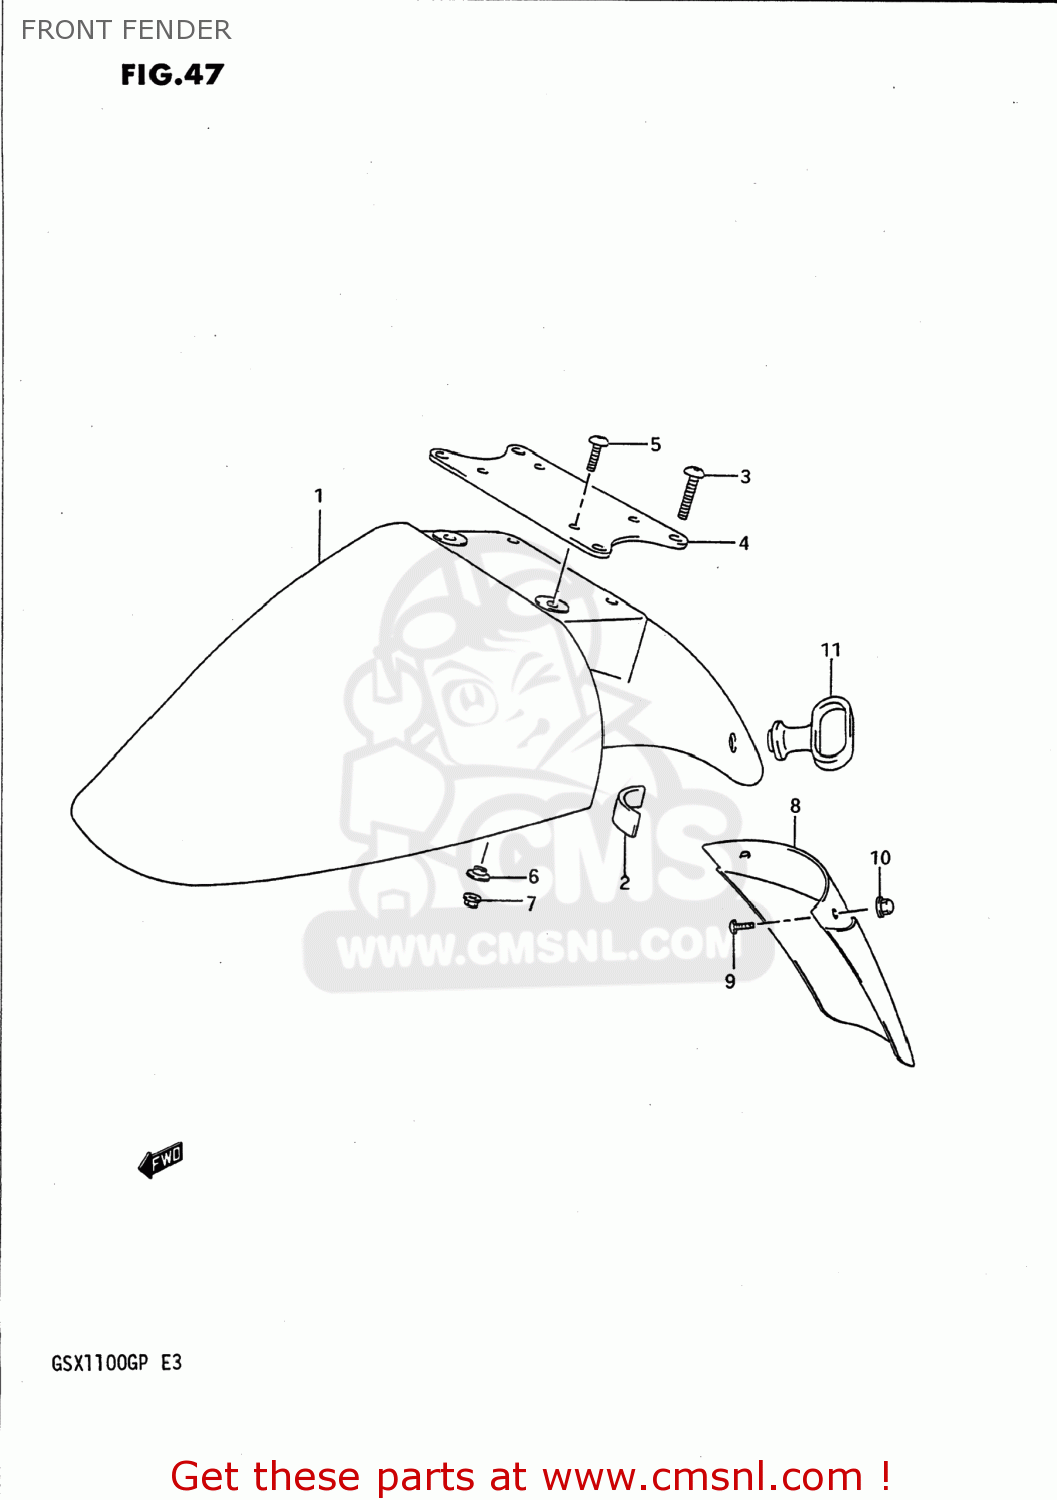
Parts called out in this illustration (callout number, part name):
1	FENDER,FRONT
2	CUSHION,BODY COWLING
3	SCREW(6X12)
4	BRACE,FR FENDER
5	SCREW(5X16)
6	WASHER
7	NUT
8	EXTENSION,FR FENDER
9	SCREW
10	NUT 5MM
11	GUIDE,CABLE
